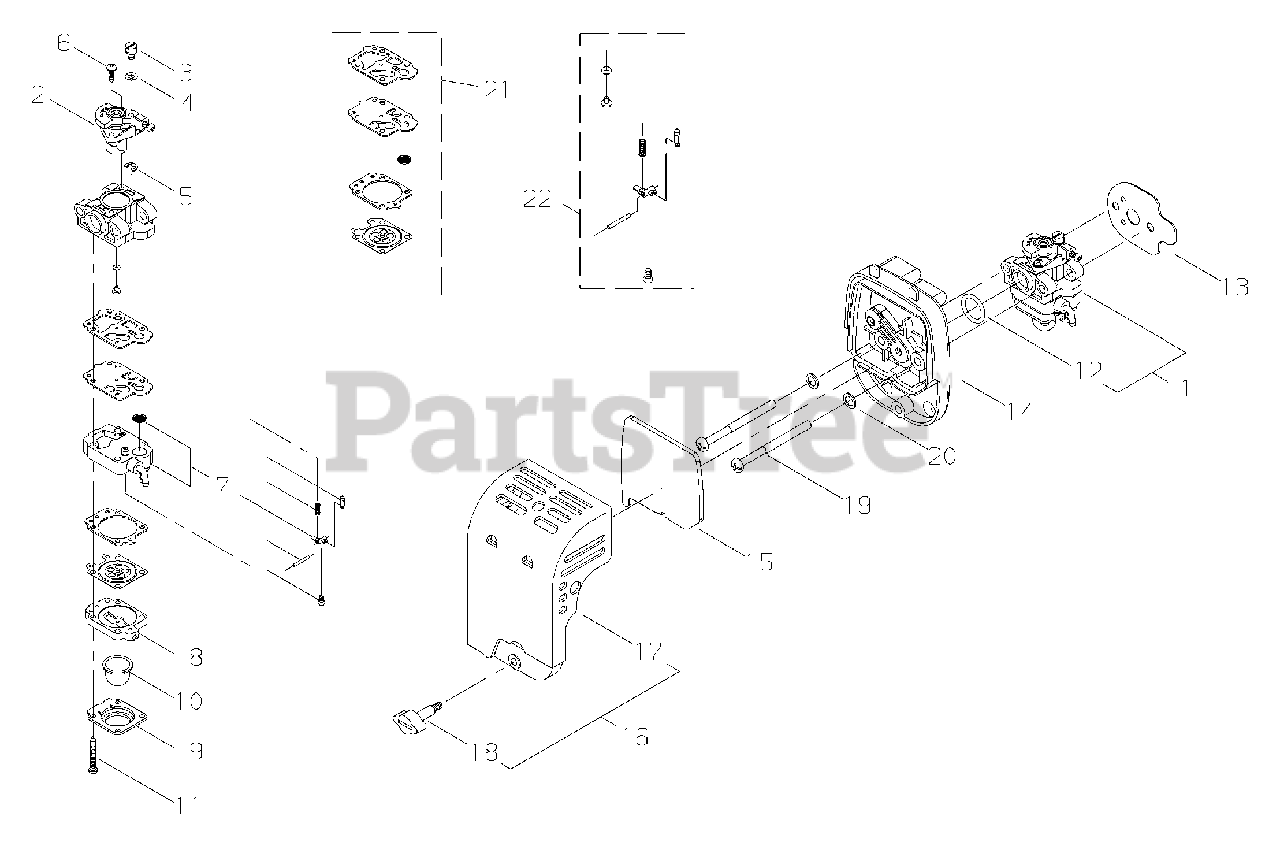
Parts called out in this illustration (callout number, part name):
1	CARBURETOR
2	THROTTLE VALVE ASSY
3	SWIVEL
4	WASHER
5	RING, RETAINING
6	SCREW
7	PUMP BODY ASSY
8	BASE, PURGE
9	RETAINER, PURGE BULB
10	BULB, PURGE
11	SCREW, PUMP COVER
12	O-RING - 15
13	GASKET, INTAKE
14	CASE, AIR FILTER
15	FILTER, AIR
16	AIR FILTER COVER ASSY
17	COVER, AIR FILTER
18	THUMBSCREW
19	SCREW - 5X60
20	WASHER - 5
21	DIAPHRAGM/GASKET KIT
22	INLET NEEDLE VALVE KIT
